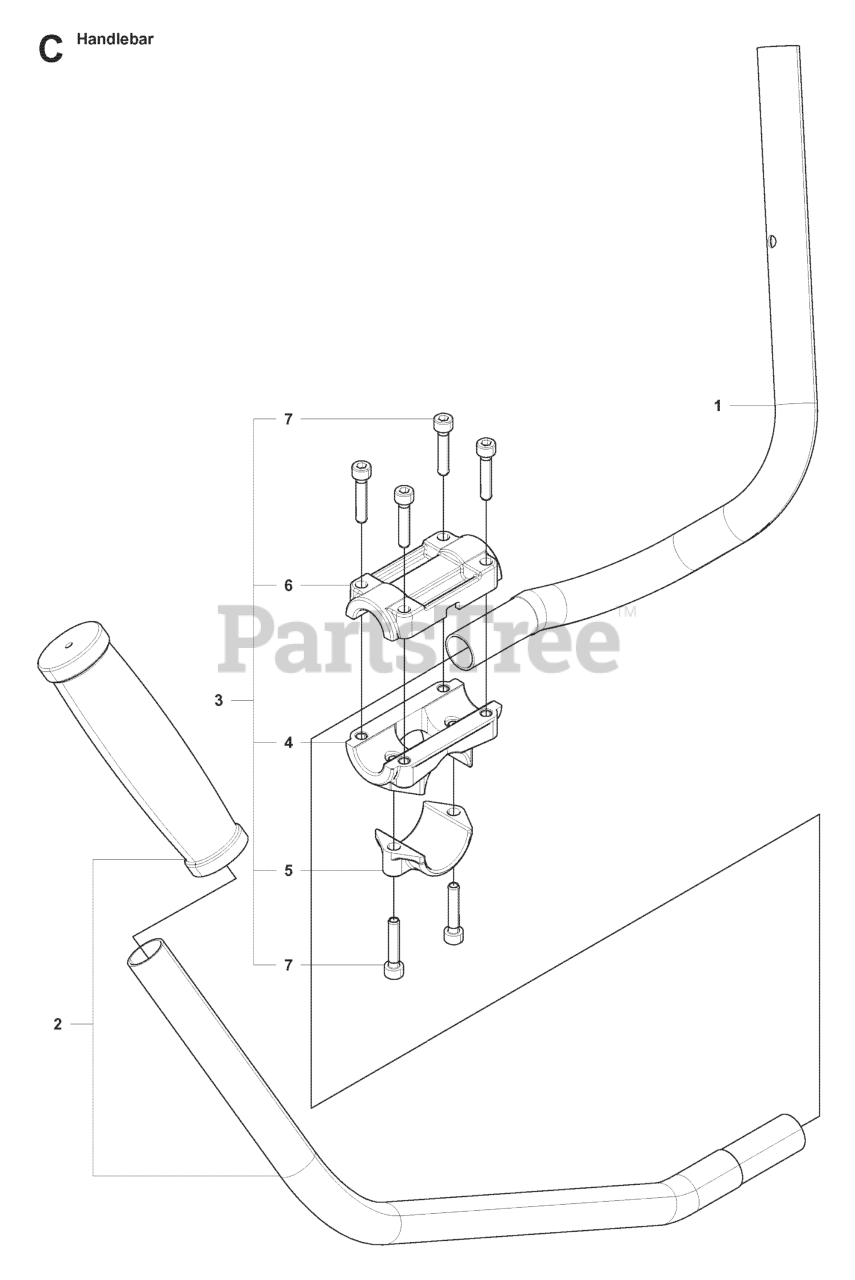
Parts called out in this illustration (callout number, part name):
1	HANDLE-R
2	HANDLE-L COMP
4	BRACKET Z354314112
5	CAP-L Z354314121
7	SCREW MC6S 5X25
